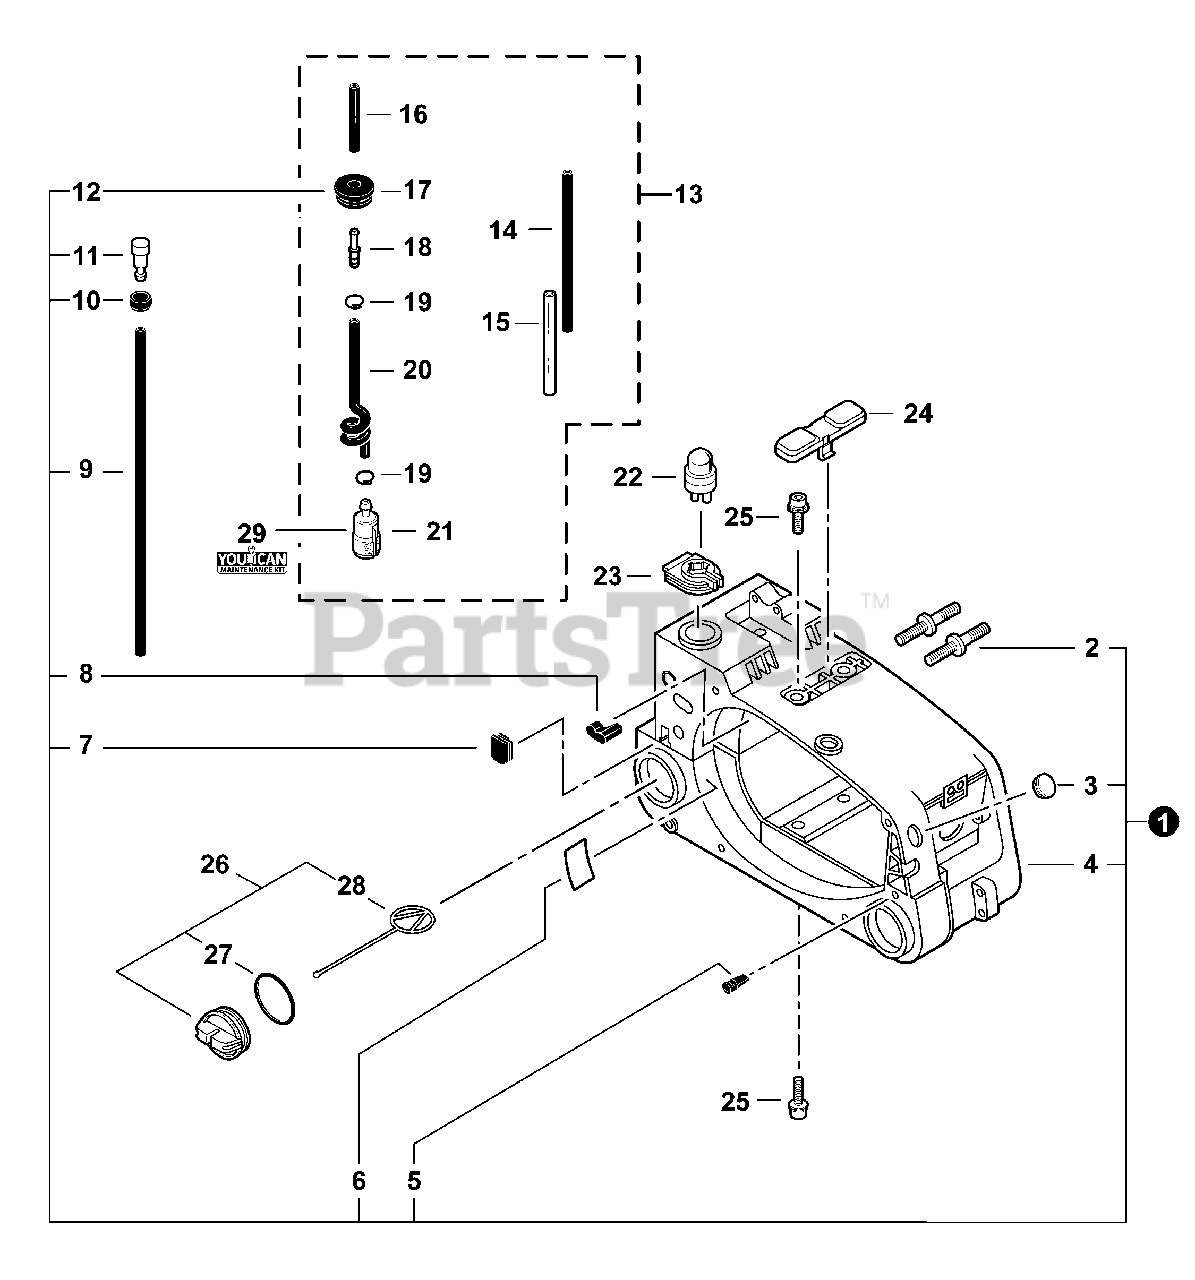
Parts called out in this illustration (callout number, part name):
1	COVER ASSY, ENGINE
2	BOLT, STUD 6
4	COVER, ENGINE
5	VENT ASSY
6	SHIELD, HEAT
9	PIPE, FUEL 3×5×150L BLACK
10	HOLDER, VENT
11	VENT ASSY
12	GROMMET, FUEL
13	FUEL SYSTEM KIT - REPOWER
14	PIPE, FUEL 3×5×70 BLACK
15	PIPE, FUEL 2×4×42 CLEAR
16	PIPE, FUEL 3×6×36 BLACK
17	GROMMET, FUEL
18	CONNECTOR, PIPE 5×3.5
19	CLIP 6.5MM
20	PIPE, FUEL 3×6×56 BLACK
21	FILTER, FUEL
22	BULB, PURGE
23	BRACKET, BULB
24	COVER, TOP
25	BOLT 5×16
26	CAP ASSY, FUEL - ORANGE
28	CONNECTOR, CAP L= 60mm
29	TUNE-UP KIT - YOUCAN™
